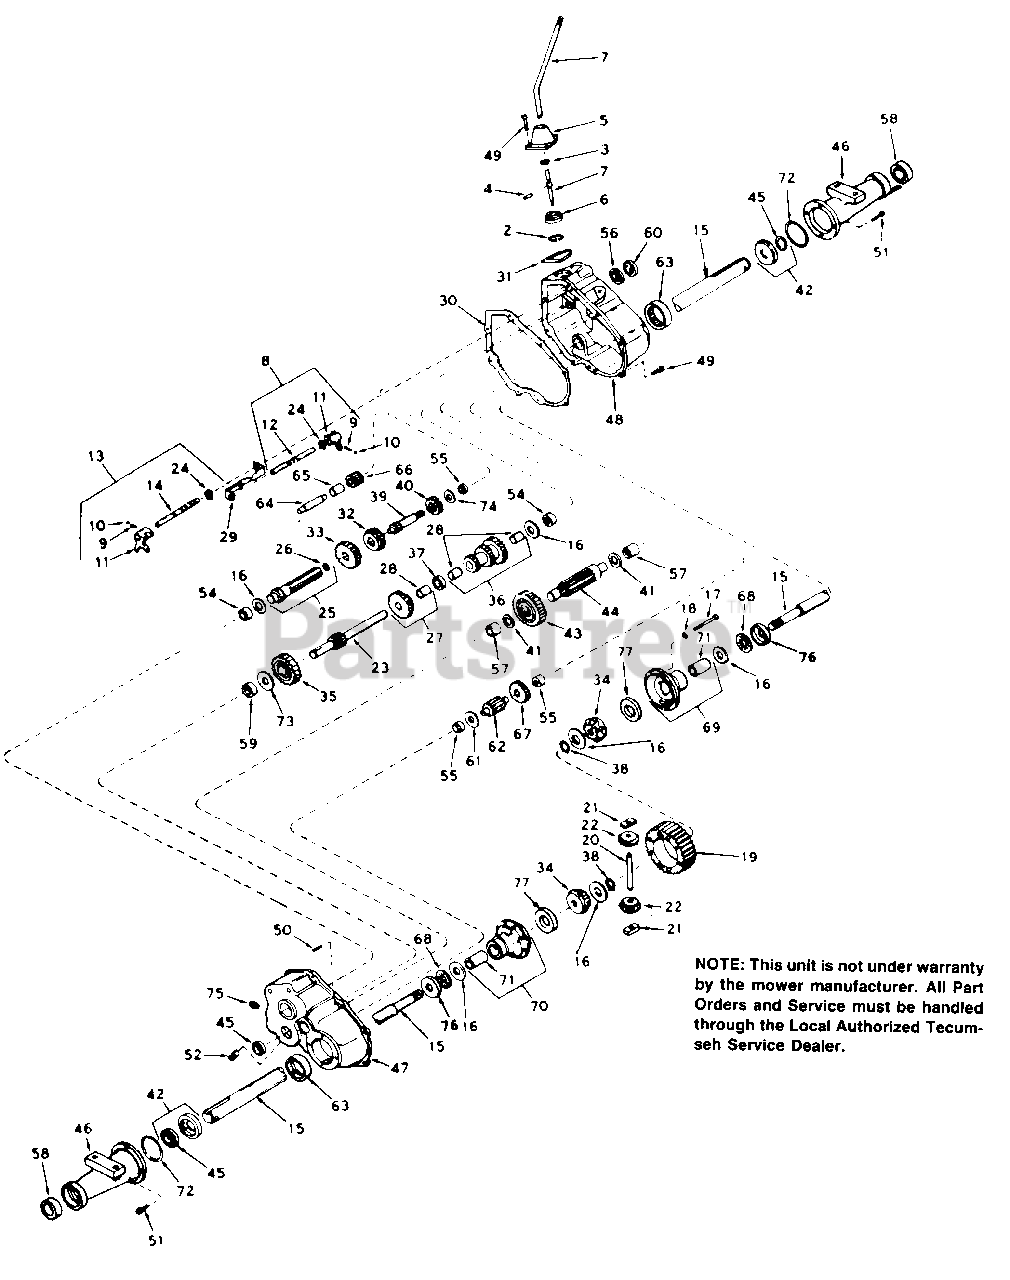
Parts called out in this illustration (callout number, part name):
2	Ring, Snap
3	Ring, Quad
4	Pin, Roll
5	Housing, Shift Lever
6	Keeper, Shift Lever
7	Lever, Shift
8	Rod Ass'y., Shift
9	Spring
10	Ball, Steel
11	Fork, Shifter
12	Rod, Shifter
13	Rod Ass'y., Shift
14	Rod, Shifter
15	Axle (18-11/32" Long)
16	Washer, Thrust
17	Scr., Hex Hd., 1/4-20 x 21/2
18	Lock Washer, 1/4"
19	Gear, Ring
20	Pin, Drive
21	Block, Drive
22	Pinion, Bevel
23	Shaft and Gear, Brake
24	Ring, Snap
25	Shaft and Bearing Ass'y., Pinion
26	Bearing, Needle
27	Gear Cluster Ass'y.
28	Bushing
29	Stop, Shifter
30	Gasket, Case and Cover
31	Gasket, Shifter LeverHousing
32	Gear, Shifting
33	Gear, Shifting
34	Gear, Bevel
35	Gear, Idler
36	Gear Cluster Ass'y.
37	Spacer
38	Ring, Snap
39	Shaft, Input
40	Spur Gear, Input Shaft
41	Washer, Thrust
42	Seal and Retainer Ass'y., Oil
43	Gear, Output
44	Pinion, Output
45	Seal, Oil
46	Housing, Axle
47	Cover Ass'y., Transaxle
48	Case Ass'y., Transaxle
49	Screw, Socket Hd., 1/4-20 x 314
50	Pin, Dowel
51	Screw, Hex Hd. Sems, 5/16-18 x 1
52	Plug, Magnetic Drain
54	Bearing, Needle
55	Bearing, Needle
56	Bearing, Ball
57	Bearing, Needle
58	Bearing, Ball
59	Bearing, Needle
60	Seal, Oil
61	Washer
62	Shaft and Pinion
63	Bearing, Needle
64	Shaft, Reverse Idler
65	Spacer, Reverse Idler
66	Idler, Reverse
67	Spur Gear (22 Teeth)
68	Bearing, Thrust
69	Carrier Ass'y., Differential
70	Carrier Ass'y, Differential
71	Bushing
72	"O" Ring
73	Washer, Thrust
74	Washer, Thrust
75	Plug, Pipe
76	Race, Thrust
77	Washer
